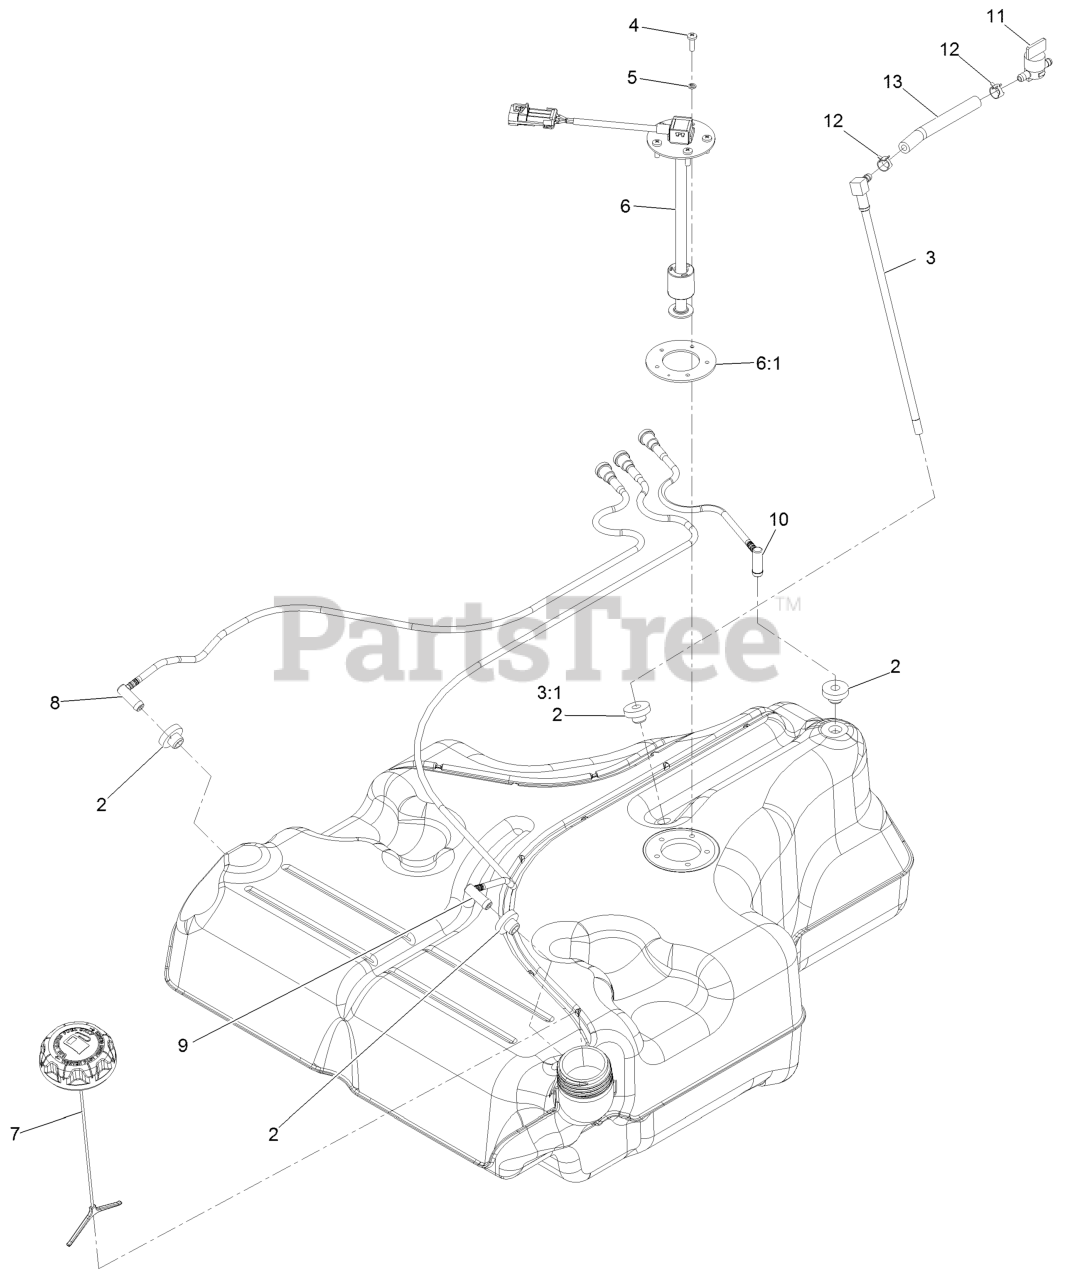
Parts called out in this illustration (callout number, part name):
2	Bushing
3	Fuel Line Kit (With Grommet)
3:1	Bushing
4	Screw-PPH #10-24 X 5/8
5	Washer-Lock 3/16
6	Sender-Fuel, Float - 12 Gal
6:1	Gasket-Sender
7	Cap-Fuel, Ratcheting
8	RH Vent Line Kit (With Grommet)
9	LH Vent Line Kit (With Grommet)
10	Rear Vent Line Kit (With Grommet)
11	Valve-Fuel
12	Clamp-Hose
13	Hose-Fuel
